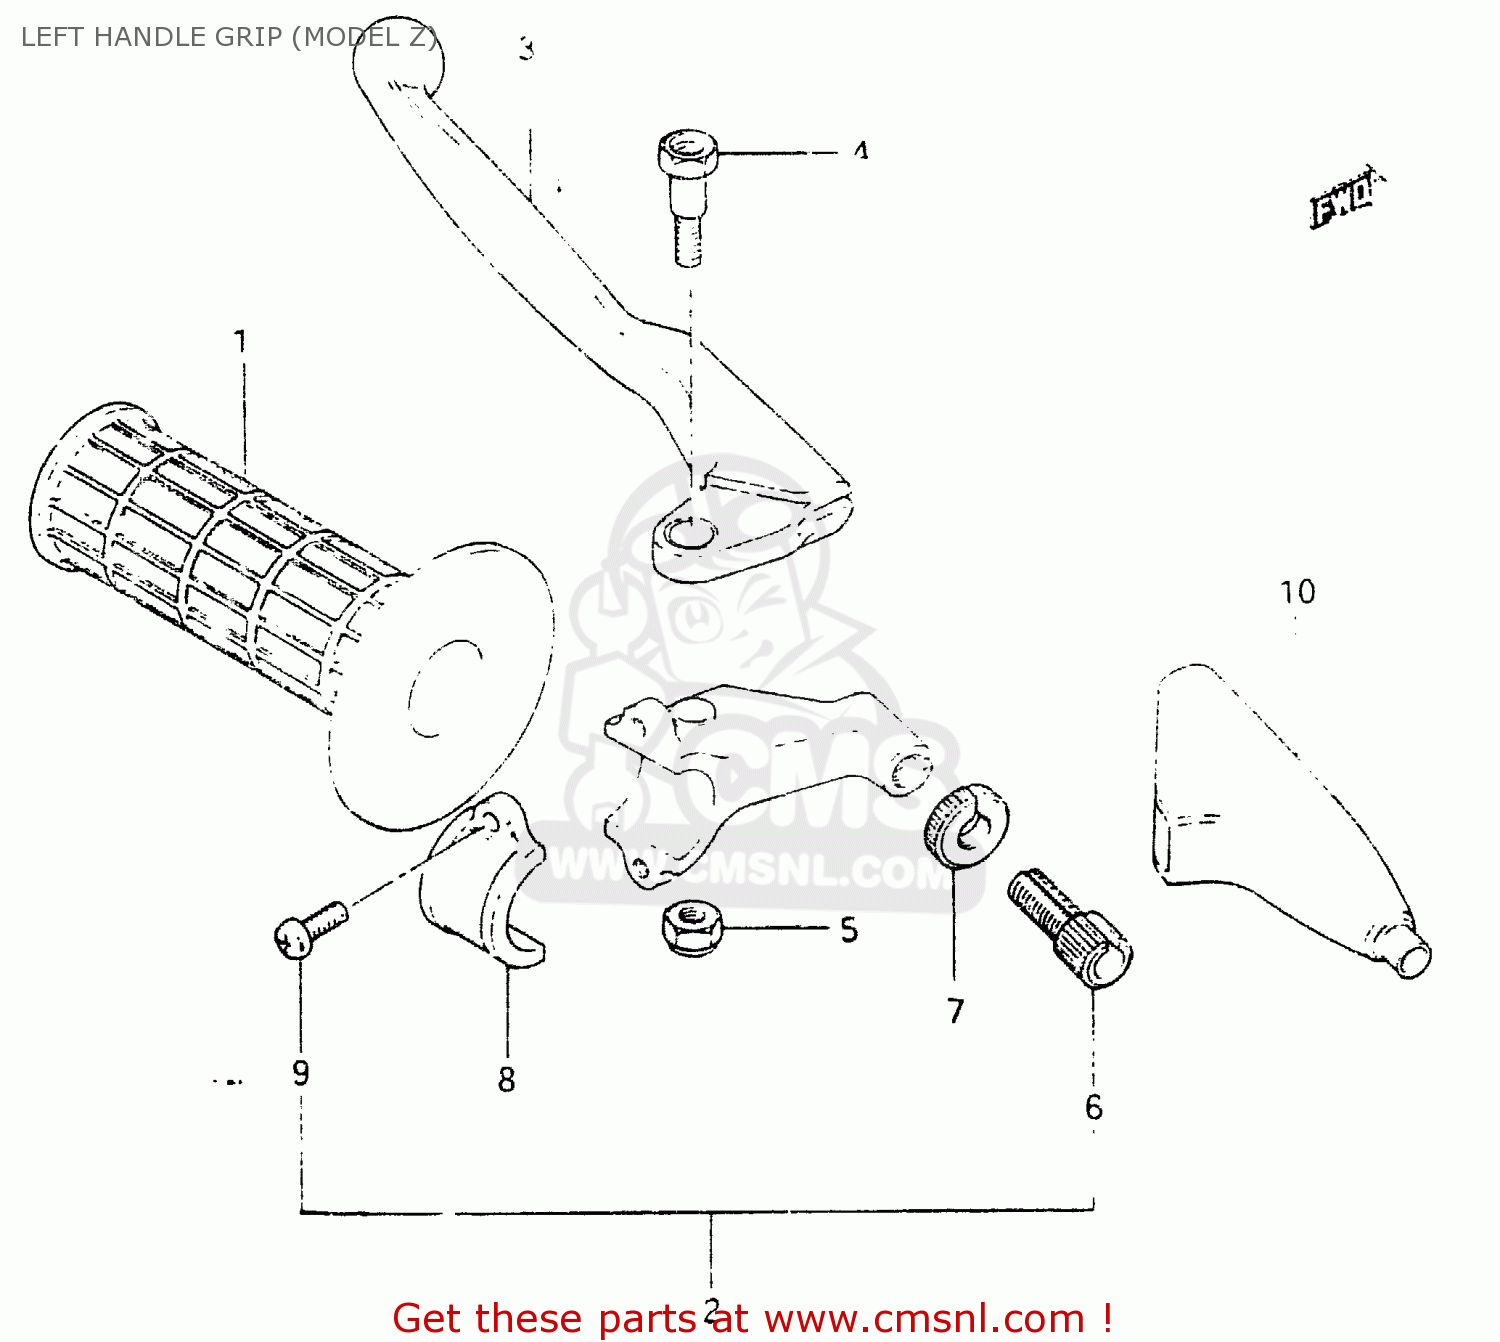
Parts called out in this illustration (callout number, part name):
1	GRIP,LEFT
2	LEVER ASSY,CLUTCH
3	LEVER,CLUTCH
4	BOLT,LEVER
5	NUT 6MM
6	ADJUSTER,CABLE
7	NUT,CABLE ADJUSTER
8	BRACKET,CLUTCH LEVER HOLDER
9	SCREW
10	COVER,CLUTCH LEVER
